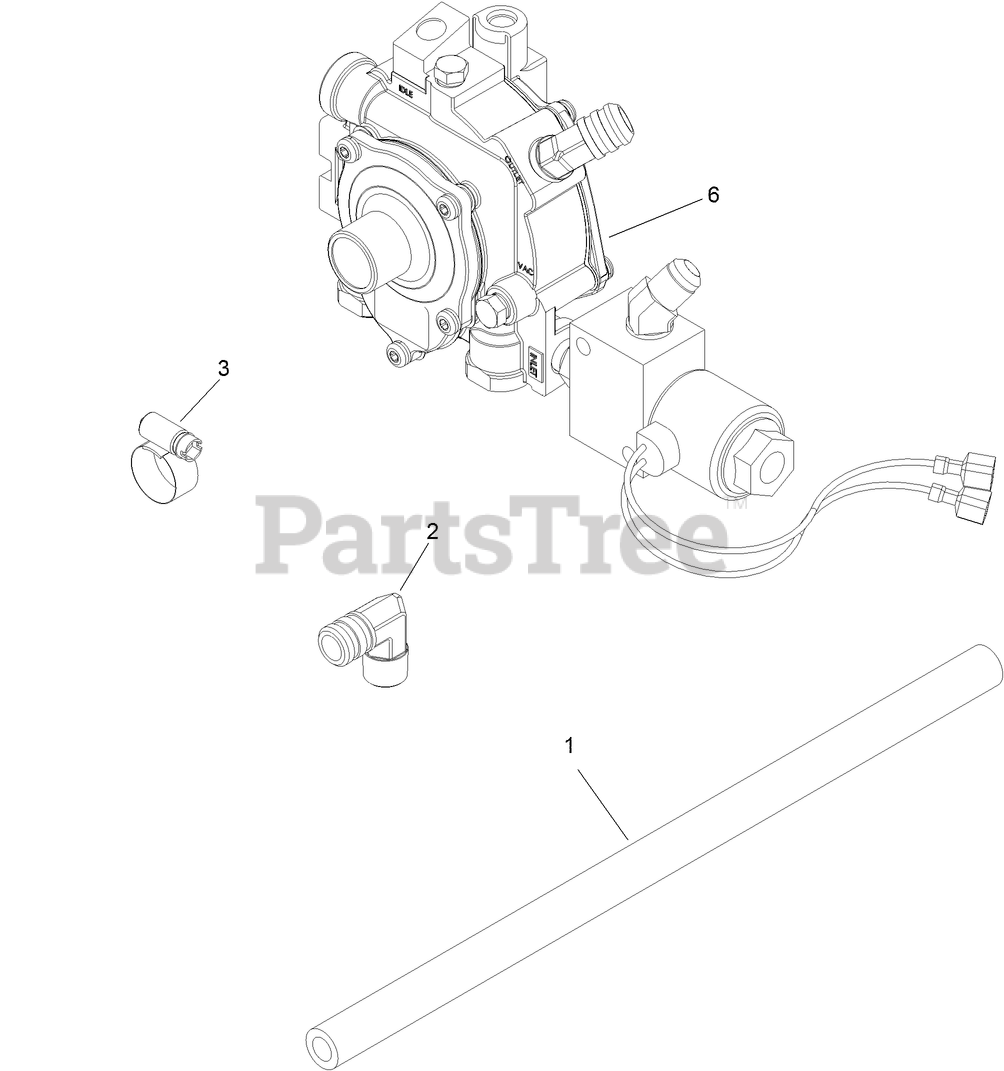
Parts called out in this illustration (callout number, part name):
1	HOSE-LPG
3	CLAMP-HOSE
6	LPG REGULATOR ASM
